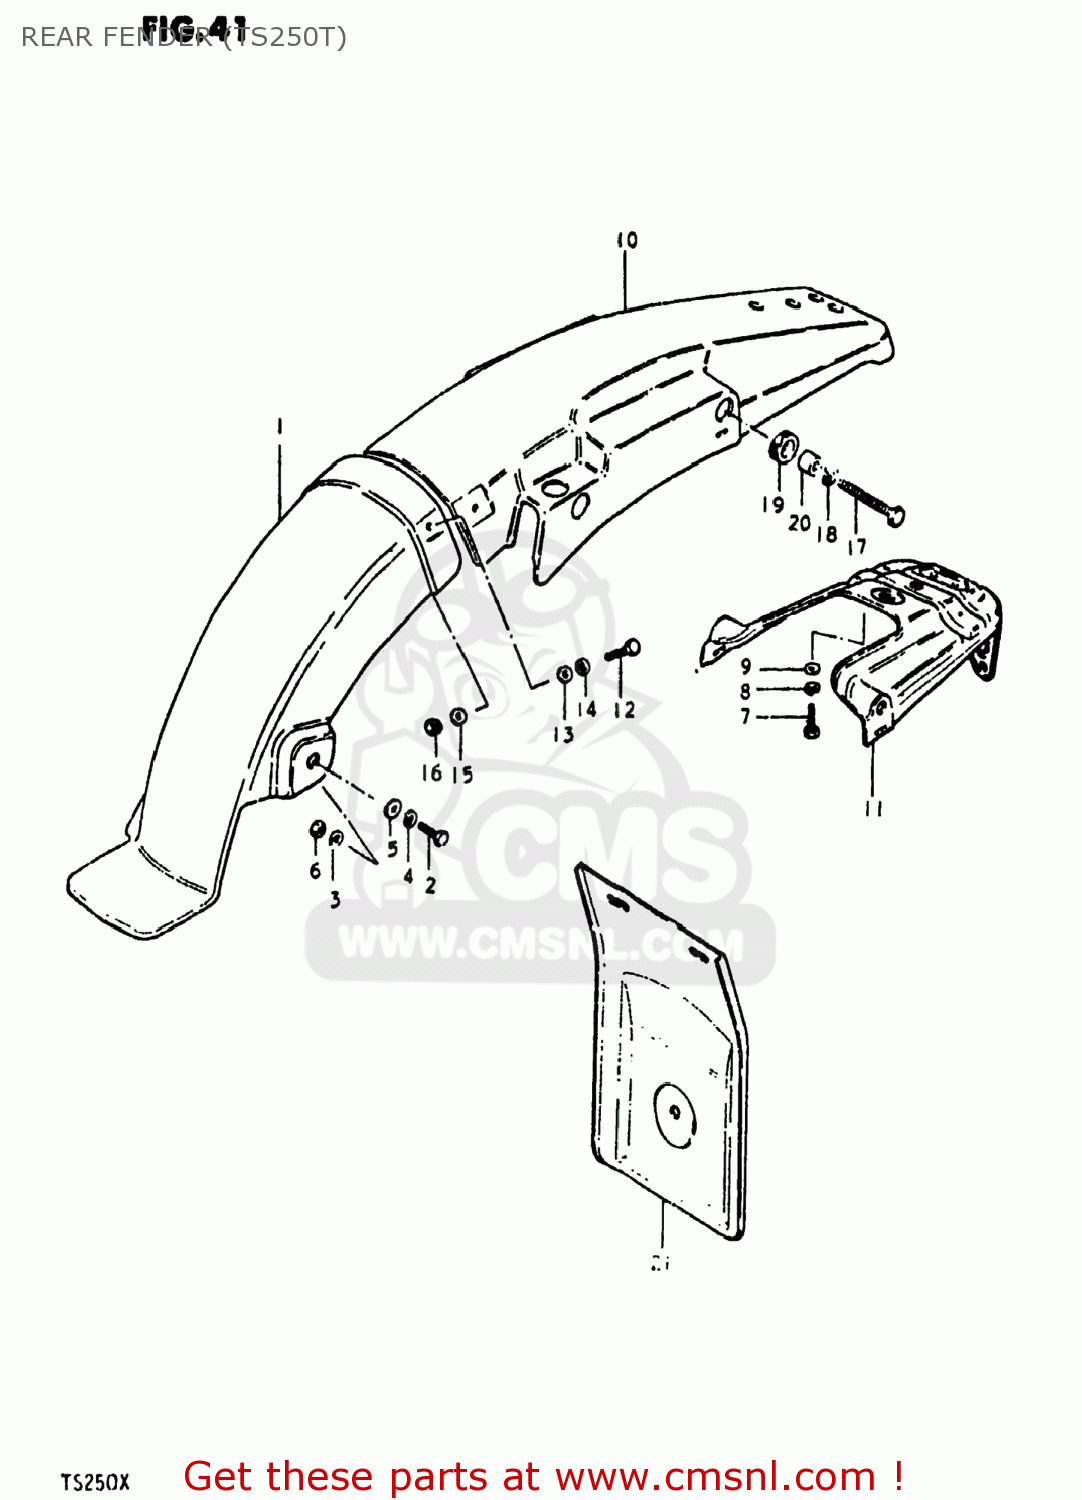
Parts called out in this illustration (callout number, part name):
1	FENDER,REAR
2	BOLT, UPPER
3	WASHER
4	LOCK WASHER
5	WASHER
6	NUT
7	BOLT
8	LOCK WASHER
9	WASHER(5.2X16X1)
10	FENDER,REAR
11	REINFORCEMENT,REAR FENDER
12	BOLT
13	WASHER (5.5X16X1.2)
14	LOCK WASHER
15	WASHER
16	NUT
17	BOLT (8X30)
18	LOCK WASHER
19	CUSHION
20	SPACER (8.2X12X7.5)
21	FLAP,RR FENDER MUD
